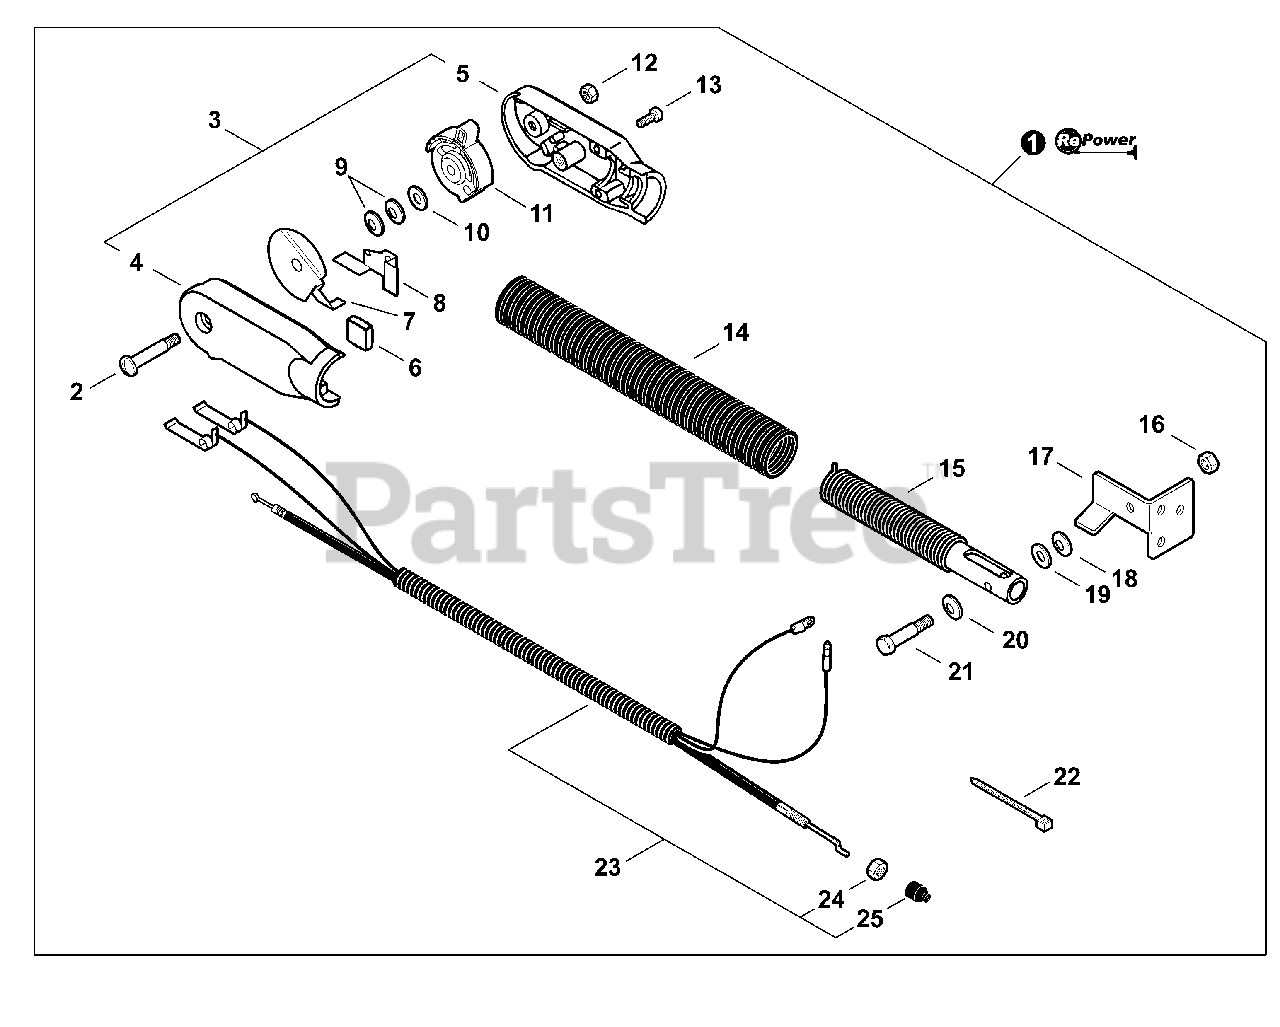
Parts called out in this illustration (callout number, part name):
1	HIP MOUNT THROTTLE CONTROL KIT
2	SCREW - 4
3	CONTROL HANDLE ASSY
4	HANDLE, CONTROL - LEFT
5	HANDLE, CONTROL - RIGHT
6	PAD, FOAM
7	TERMINAL - GROUND
8	TERMINAL - GROUND
9	WASHER - SPRING
10	WASHER - 6
11	LEVER, THROTTLE CONTROL
12	LOCKNUT - 4
13	SCREW - 5×20
15	TUBE, SPRING
16	LOCKNUT - 1/4"
17	BRACKET
18	WASHER - SPRING
19	WASHER - 8
20	WASHER - SPRING
21	BOLT - 6
22	TIE, CABLE - SMALL
23	CONTROL CABLE ASSY
24	LOCKNUT - 6
25	CAP, DUST
